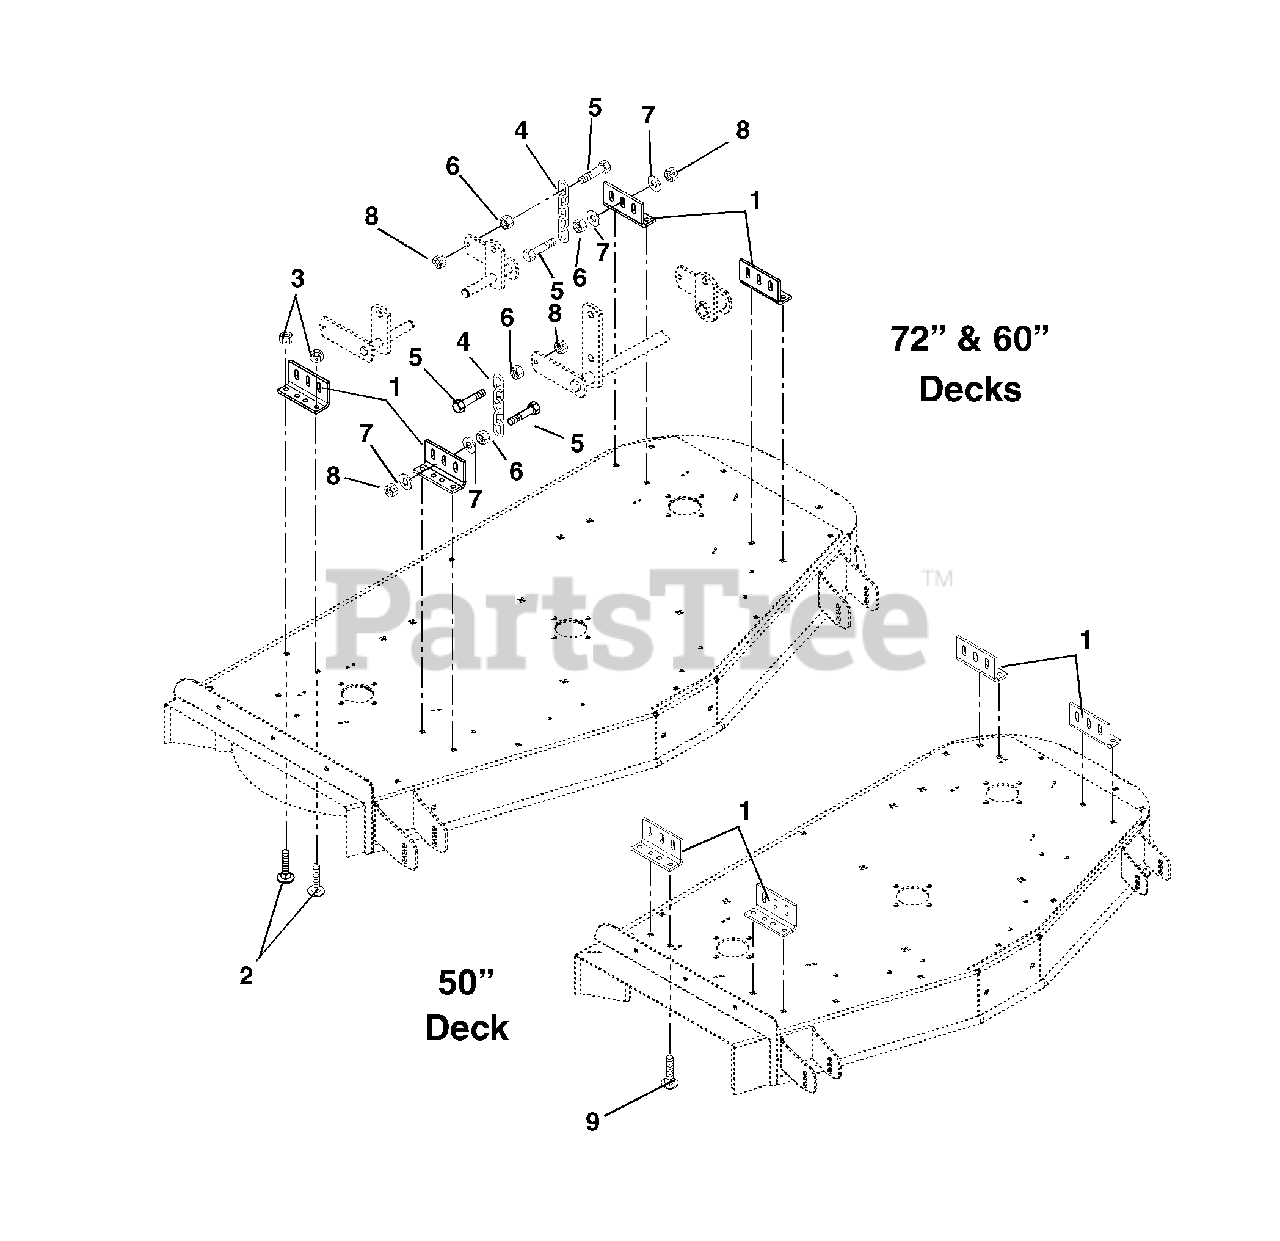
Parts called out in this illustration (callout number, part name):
1	Bracket, Mower Mounting
2	Bolt-Round Head Square Neck .38-16 x 1.25 Grade 2 (60" Deck)
2	Bolt-Round Head Square Neck .38-16 x 1.25 Grade 2 (50" Deck)
3	Nut-Locking-Nylon .38-16
4	Chain, Link
5	Bolt-Hex .38-16 x 1.50 Grade 5
6	Nut-Hex .38-16
7	Washer-Flat-Steel .406 x .812 x .065
8	Nut-Locking-Center .38-16
9	Bolt-Round Head Square Neck .38-16 x 1.50 Grade 2 (50" Deck)
